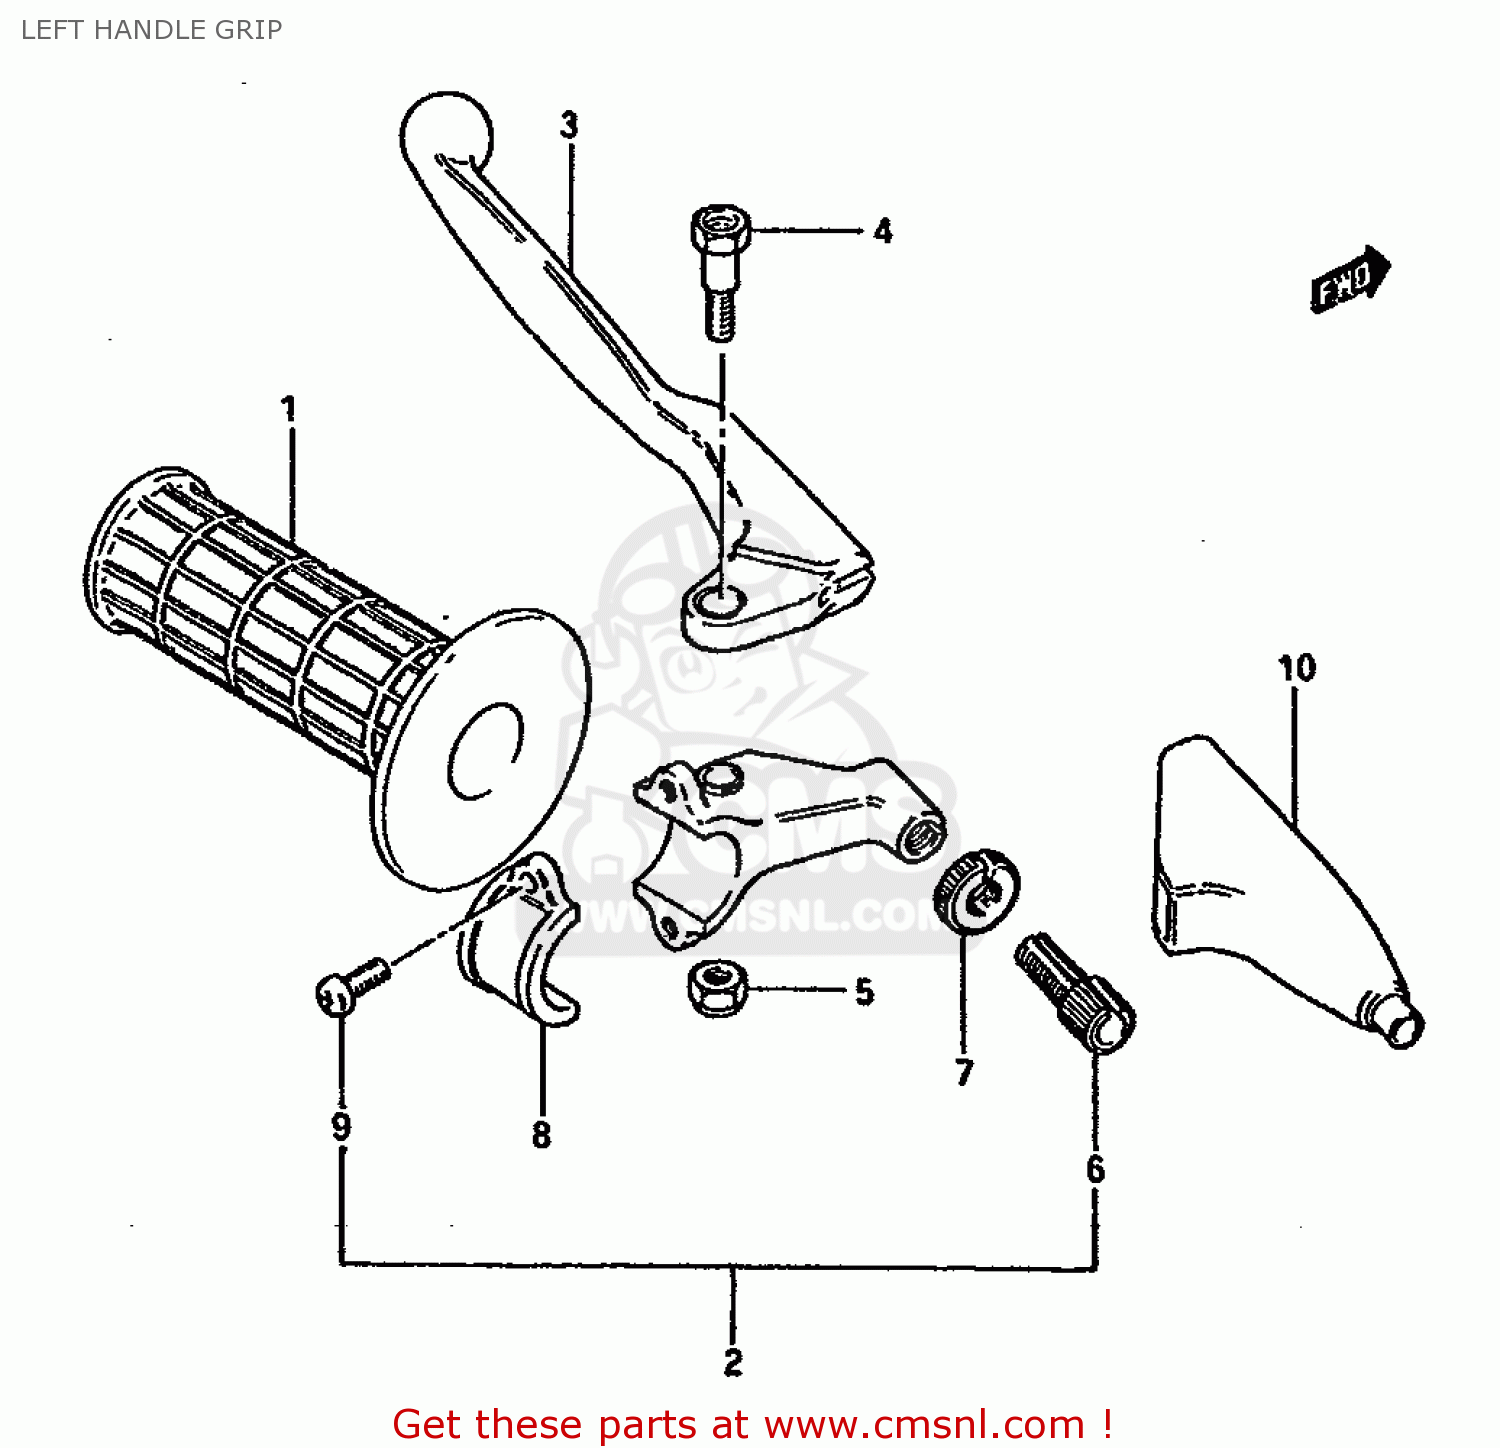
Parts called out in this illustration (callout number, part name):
1	GRIP,LEFT
2	LEVER ASSEMBLY
3	LEVER,CLUTCH
4	BOLT,LEVER
5	NUT
6	ADJUSTER,CABLE
7	NUT,CABLE ADJUSTER LOCK
8	HOLDER,LEVER
9	SCREW (5X14)
10	COVER,CLUTCH LEVER
